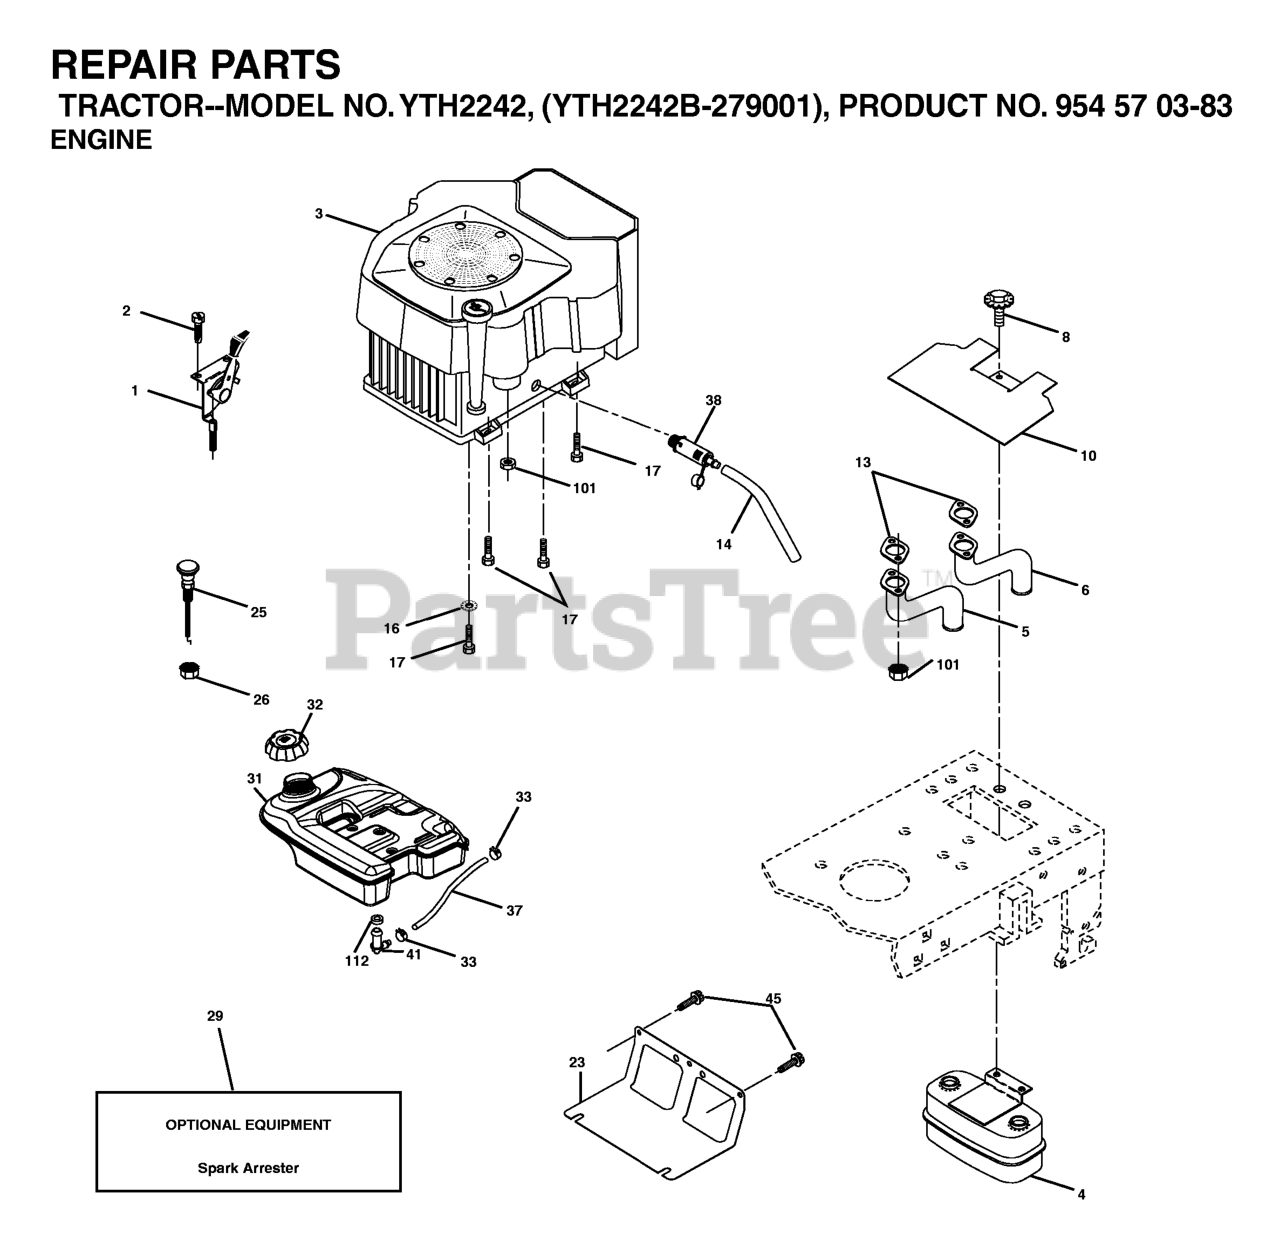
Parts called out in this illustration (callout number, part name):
1	CONTROL,TH/CH FLAG
2	SCREW
4	MUFFLER.TWIN.CYL.LOW.TONE
5	RP.PIPE-EXHAUST LH
6	RP.PIPE-EXHAUST RH
8	BOLT.5/16-18UNCX3/4 W/SEMS.BLK
10	RP SHIELD HEAT MUFFLER
13	GASKET.EXHAUST.KOHL.CV18-CV26
14	TUBE, DRAIN OIL ASM.
16	LOCKWASHER
17	SCREW 3/8-16 X 1-1/2
23	SHIELD.BROWNING.DBR.GUARD
25	CONTROL, CHOKE
26	Nut Keps 3/8 - 24 UNF
29	KIT.SPARK ARRESTOR 794945 B&S
31	4.0 REAR FUEL TANK
32	TANK CAP
33	HOSE CLAMP
37	REPL BY 532 00 85-43
38	PLUG DRAIN OIL EASY
41	STEM FUEL TANK
45	SCREW, 3/8-16X3/4
101	FLANGE NUT
112	BUSHING OUTLET T
